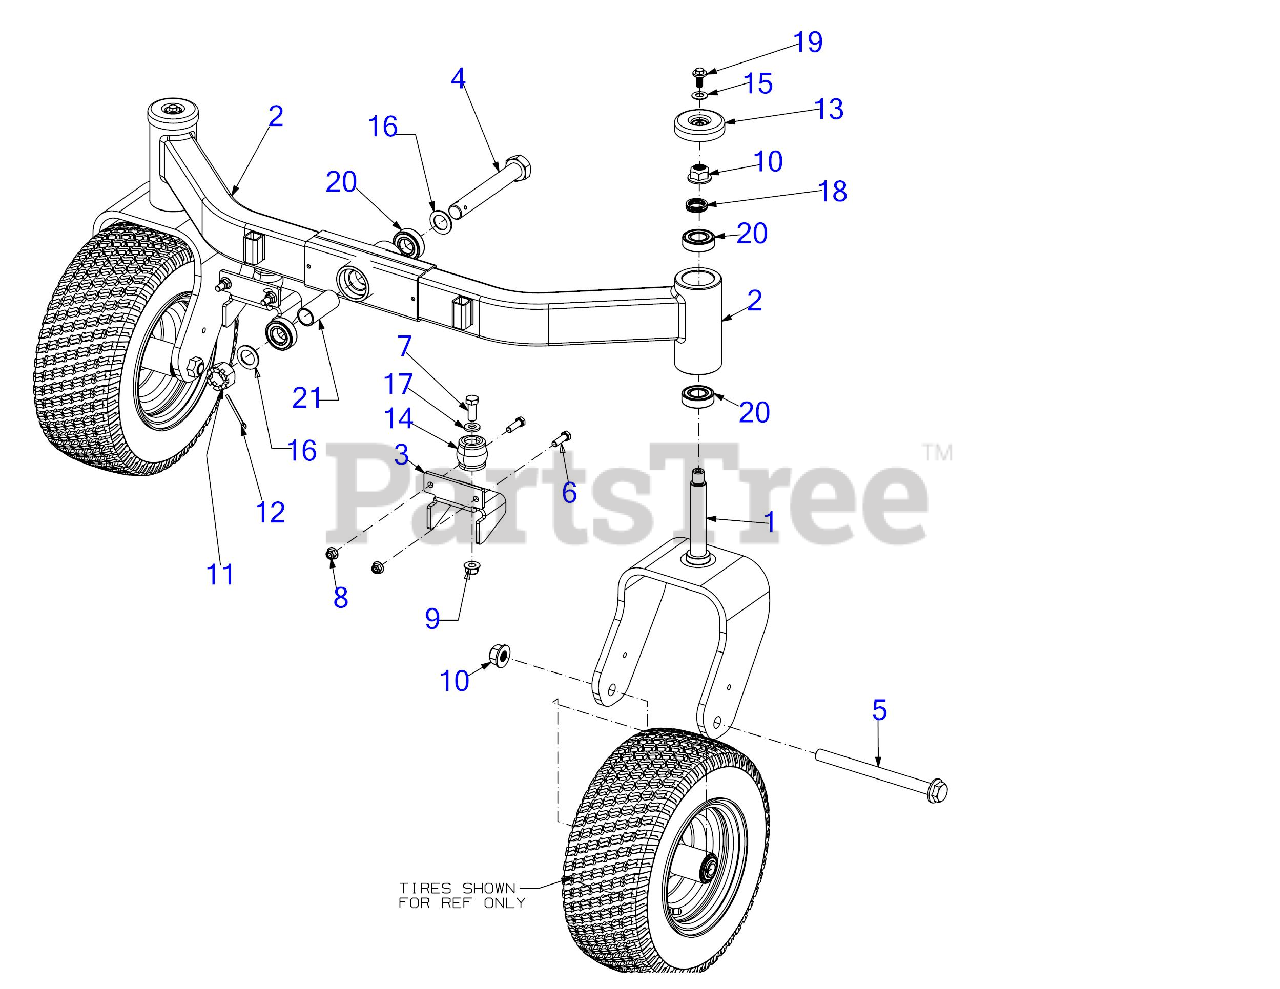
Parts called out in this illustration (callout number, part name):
4	HEX HEAD SCREW 1-14 X 7 GR5
5	SCREW 3/4-16 x 9.00 GR5
6	SCREW 3/8-16 x 1.25 GR5
7	SCREW 1/2-13 x 1.25 GR5
10	FLANGE LOCK NUT 3/4-16 TOP LOCK
11	CASTLE NUT 1.0-14 GR5
12	COTTER PIN
13	AXLE CAP 3"
14	AXIAL BUMPER
15	BELL WASHER
16	FLAT WASHER 1.031 X1.62 X.095
17	FLAT WASHER .510 x 1.000 x .125
18	WAVE WASHER
20	BALL BEARING 1.0 X 52 X 15
21	SPACER 1.00 X 1.25 X 2.99
